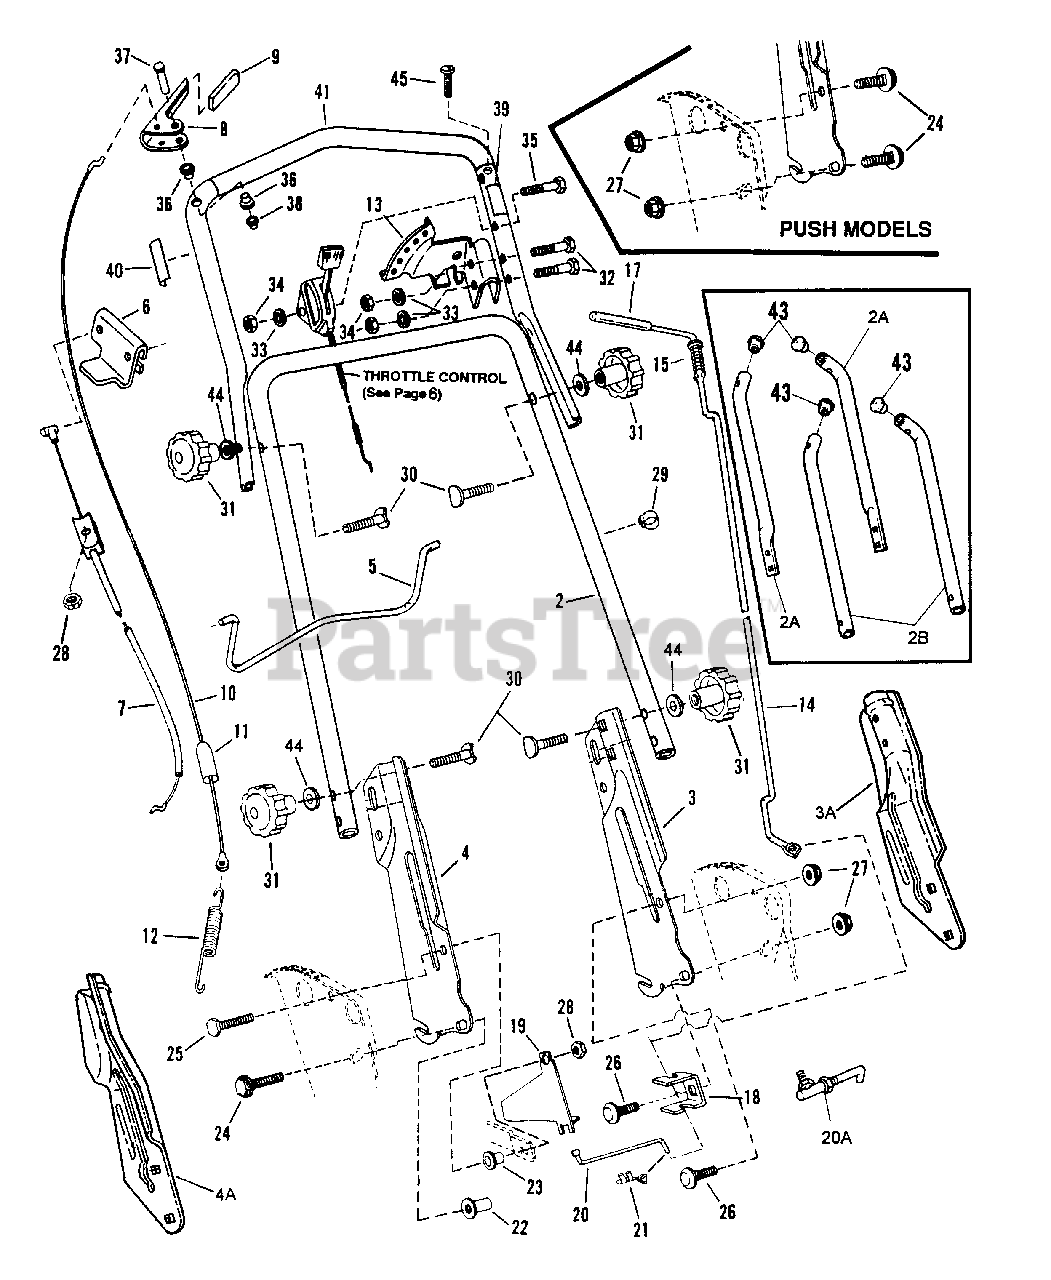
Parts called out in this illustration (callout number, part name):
1	HANDLE, Upper
2	HANDLE, Middle (15.5" Wide ID)
2A	HANDLE, Middle (32" x 7/8", Flat Bottom 2 Hole) 13.8" Wide ID
2B	HANDLE, Middle (24" x 7/8") 13.8" Wide ID
3	HANDLE, Lower Left Hand
3A	HANDLE, Lower Left Hand
4	HANDLE, Lower Right Hand
4A	HANDLE, Lower Right Hand
5	BAIL, OPC Control (16.6" Wide)
6	CLIP, Blade Control
7	CABLE, Blade Control 50.51"
7	CABLE, Blade Control 48.65"
7	CABLE, Blade Control 74.05"
8	HANDLE, Wheel Drive
9	GRIP, Wheel Drive Handle
10	CABLE, Clutch Pull (Z-BEND) 41.44"
11	COVER, Vinyl
12	SPRING, Clutch
13	SECTOR, Speed
14	LEVER, Speed Control 38"
15	SPRING, Speed Control
16	WASHER, 3/8" Flat
17	GRIP, Speed Control Handle
18	ANCHOR, Speed Control
19	GUIDE, Lower V-Belt
20	ROD, Transfer
20A	ASSEMBLY, Transfer Rod
21	CLIP, Transfer Rod
22	TEE-NUT, 5/16-18
23	BUSHING, Differential
24	BOLT, 5/16-18 x 3/4" Flange Lock, Gr. 5
25	SCREW, 5/16-24 x 1" Hex Cap, Gr. 5
26	BOLT, 5/16-18 x 5/8" Carriage, Gr. 5
27	NUT, 5/16-18 Hex Flange Lock, Gr. 5
28	NUT, 5/16-24 Center Lock, Gr. 5
29	CLIP, Cable/Wiring
30	SCREW, 5/16-18 x 1-7/8 Curved Hd Gr. 2
31	KNOB, 5/16-18
32	SCREW, 1/4-28 x 1-3/8 Hex Cap, Gr. 5
33	WASHER, 1/4 Internal Tooth Lock
34	NUT, 1/4-28 Hex, Gr. 5 or B
35	SCREW, 1/4-28 x 1-3/4" Hex Cap, Gr. 5
36	BUSHING
37	PIN, Clutch Handle
38	PUSH-NUT (for handle pin)
39	DECAL, Blade Control (LH Side)
40	DECAL, Wheel Control (RH Side)
41	GRIP, Foam
43	PLUG
44	WASHER, 5/16 Internal Tooth Lock
45	SCREW, 5/16-24 x 1-1/2" Machine, Gr. 5
